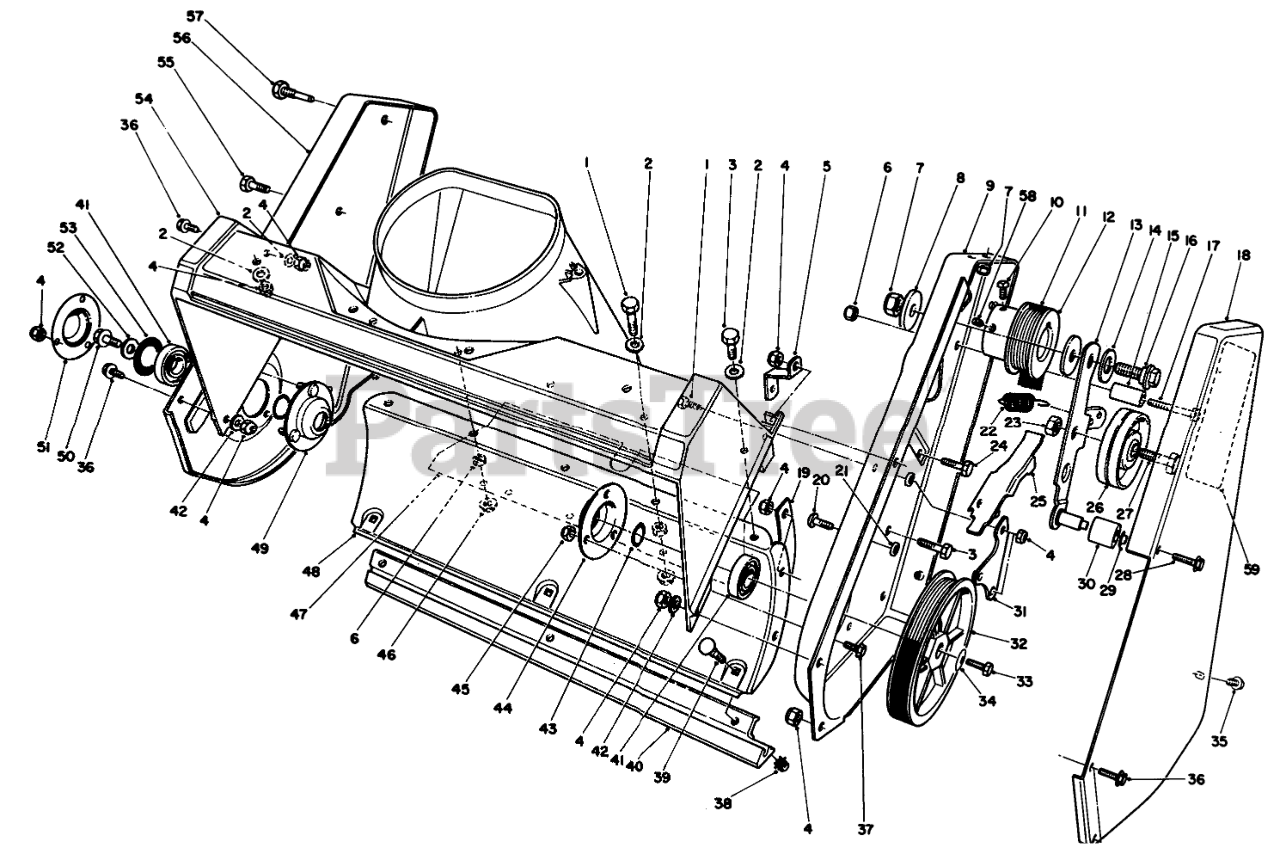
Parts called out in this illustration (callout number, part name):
1	SCREW-HH
2	WASHER-FLAT
3	SCREW-HH
4	NUT-LOCK, NI
5	BRACKET-HOUSING
6	NUT-HEX, SIDE DEFORM
7	NUT-LOCK, NI
8	WASHER-PIVOT
9	Sideplate-L.H.
10	SCREW-SQH
11	BELT - DRIVE
12	ENGINE PULLEY
13	Idler Arm Assembly (Incl. Ref. #29 & 30)
14	WASHER
15	SLEEVE-GUIDE, BELT
16	SCREW-SHOULDER
17	SCREW-HH
18	Cover-Drive
19	BRACKET-HOUSING, LOWER
20	SCREW-HSBH
21	SPACER-PLATE, PIVOT
22	SPRING-EXTENSION
23	NUT-LOCK, CONE
24	SCREW-HH
25	BRAKE-ARM
26	PULLEY-IDLER
27	SCREW-HH
28	SCREW-HWH, TAP
29	NUT-PUSH
30	ROLLER-BRAKE
31	PIVOT PLATE ASM
32	ROTOR PULLEY ASY
33	SCREW-HH
34	WASHER-BELLEVILLE
35	SCREW
36	SCREW-HWH
37	SCREW-SHH
38	NUT-KEPS
39	SCREW-CARR
40	SCRAPER
41	BEARING-BALL
42	WASHER-FLAT
43	WASHER-THRUST
44	FLANGE-BEARING
45	NUT-LOCK, NI
46	NUT-LOCK, HHF
47	BOTTOM COVER
48	Housing-Lower
49	FLANGE-BEARING
50	SCREW-HHF
51	Trough
52	WASHER-FLAT
53	WASHER-RUBBER
54	HOUSING
55	SCREW-HH
56	Sideplate-RH
57	PIN-ROTOR
58	SCREW-HSH
59	DECAL
